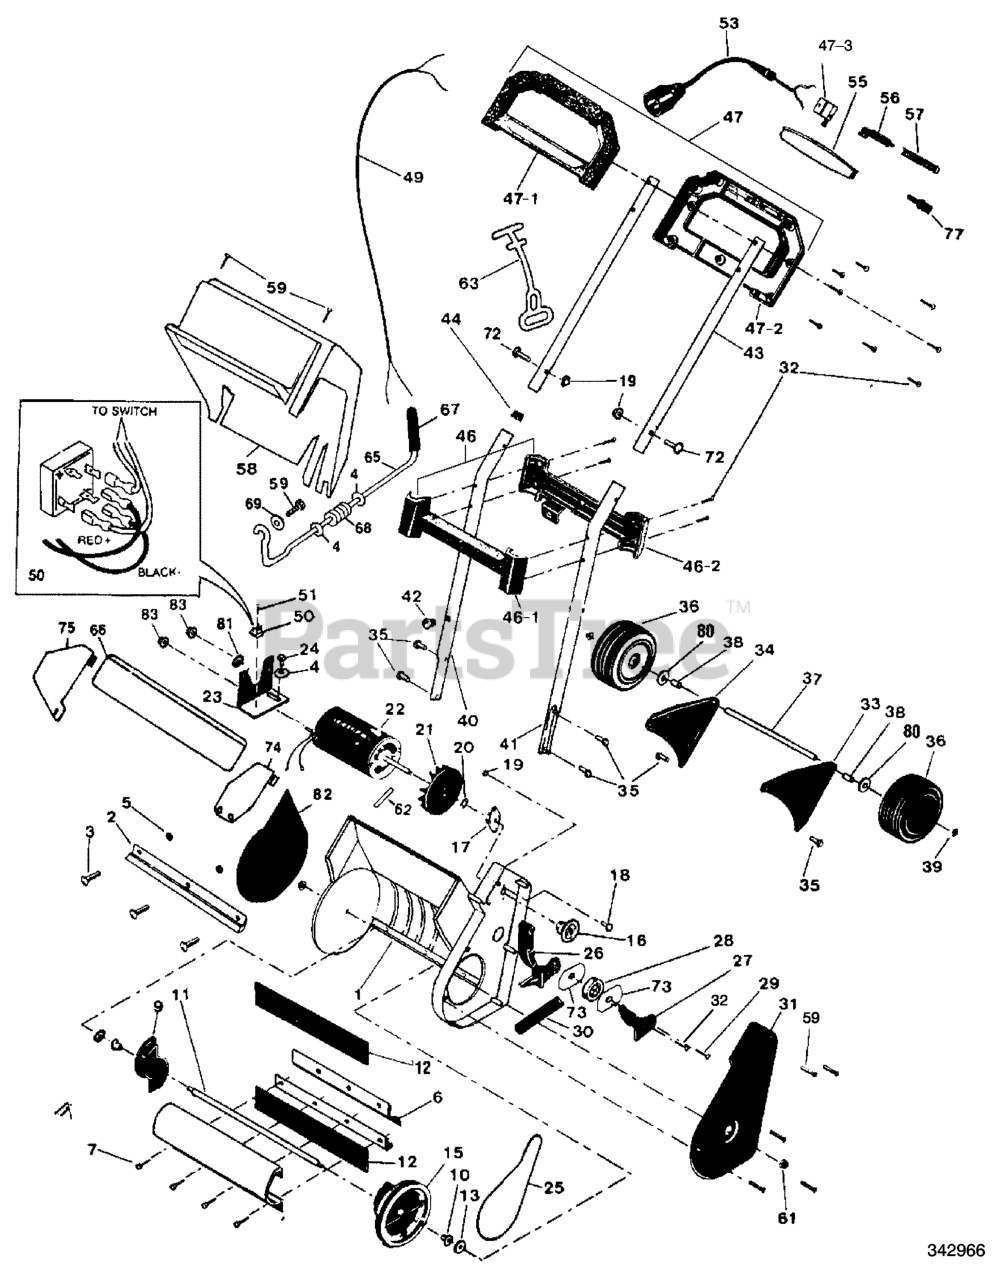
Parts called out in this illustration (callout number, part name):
1	Housing, Scoop
2	Blade, Scraper
4	Washer, Flat
5	Nut, 1/4-20
6	Segment, Drum
9	Cap, Drum End
10	Bearing, Bronze
11	Shaft, Paddle
12	Paddle, Auger
13	Washer, Flat
15	Pulley, Driven
16	Pulley, Drive
17	Bearing, Self Align
18	Screw, 1/4-20
19	Nut, 1/4-20
20	Ring, Retainer
21	Fan, Motor
22	Motor, 120V
23	Bracket, Motor Mount
24	Screw, 1/4-14x0.75
25	Belt, Drive
26	Arm, Idler
27	Bearing, Retainer Idler
28	Bearing, Ball
30	Spring Idler
31	Cover, Left Drive Housing
33	Bracket, Left Wheel
34	Bracket, Right Wheel
35	Screw
36	Wheel, 15"
38	Spacer, Wheel
39	Nut, Push On Cap
40	Handle, Right Lower
41	Handle, Left Lower
42	Bushing
43	Handle, Upper
44	Protector, Harness
45	Harness, Protector
46	Set, Handle Assist
46-1	Order Set
46-2	Order Set
47	Set, Handle Grip
47-1	Order Set
47-2	Order Set
47-3	Order Set
49	Harness, Wire
50	Rectifier, Full Wave
53	Connecting Lead
55	Bar, Switch
56	Lever, Switch
57	Spring, Switch
58	Cover, Motor
62	Pin, Grooved
63	Strain Relief, Cord
65	Rod, Discharge
66	Slider, Vane
67	Grip, Hand Vinyl
68	Spring, Actuator Rod
69	Washer, Flat
73	Retainer, Belt
74	Deflector, Outer
75	Deflector, Inner
77	Key, Hi-Pro
80	Washer, Flat
81	Grommet
82	Cover, Right Housing
